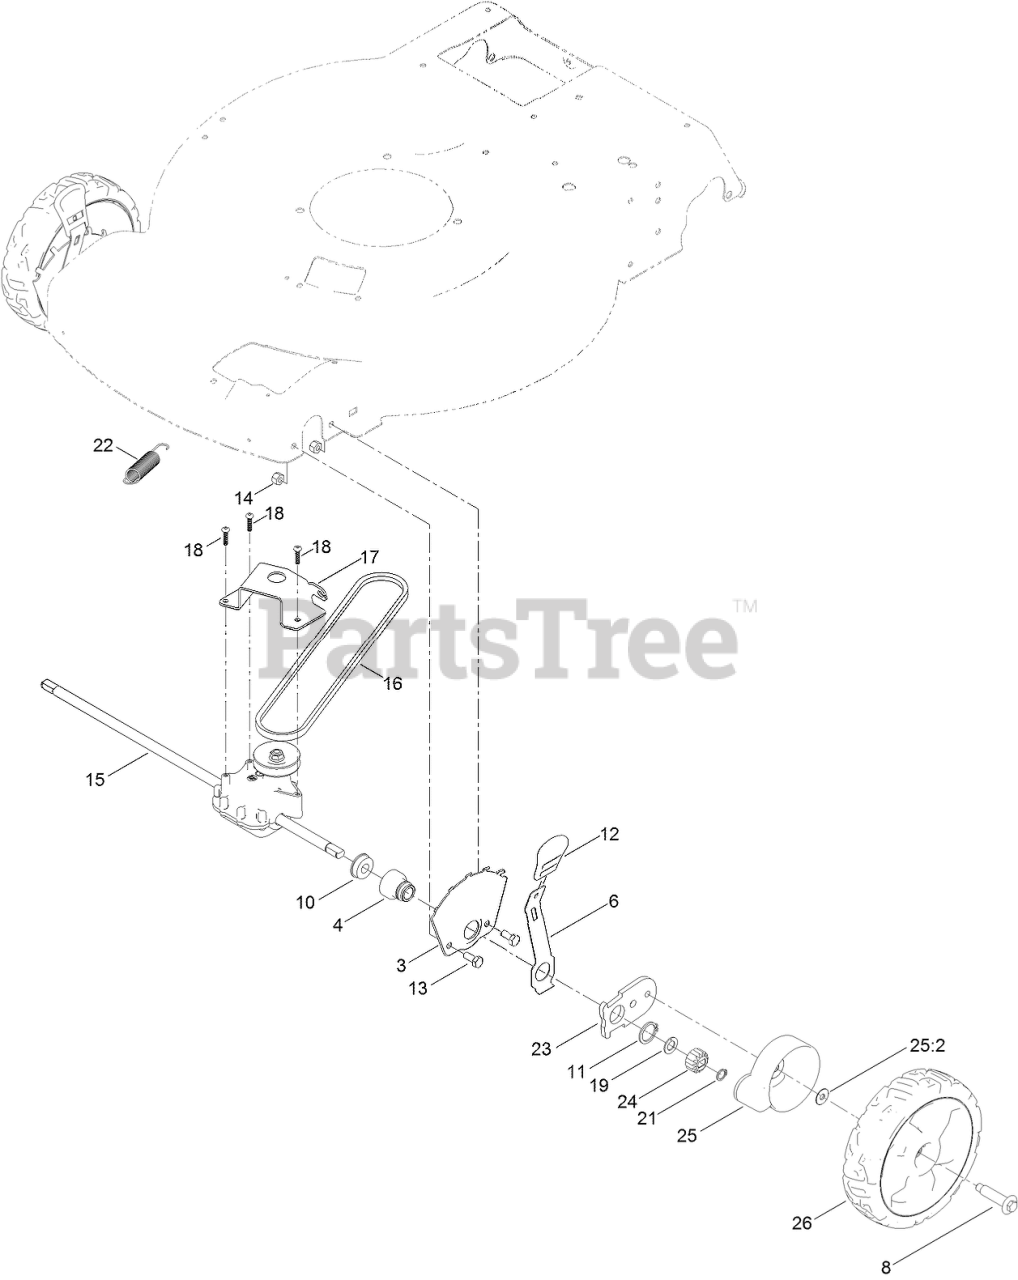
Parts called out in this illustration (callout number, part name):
3	PLATE-HOC, FRONT
4	RETAINER-BEARING, HOC
6	Arm-Spring
8	BOLT-SHOULDER
10	BEARING-BALL
11	RING-RETAINING
12	KNOB-HOC
13	SCREW-HH
14	NUT-LOCK, NI
15	TRANSMISSION
16	V-BELT
17	BRACKET-TRANSMISSION
18	SCREW-PLASTITE
19	WASHER-THRUST
21	RING-RETAINING
22	SPRING-EXTENSION
23	ARM-PIVOT, FRONT
24	GEAR-PINION, 15T
25	GEAR COVER ASM
25:2	WASHER-STEPPED
26	WHEEL GEAR ASM, 8IN
